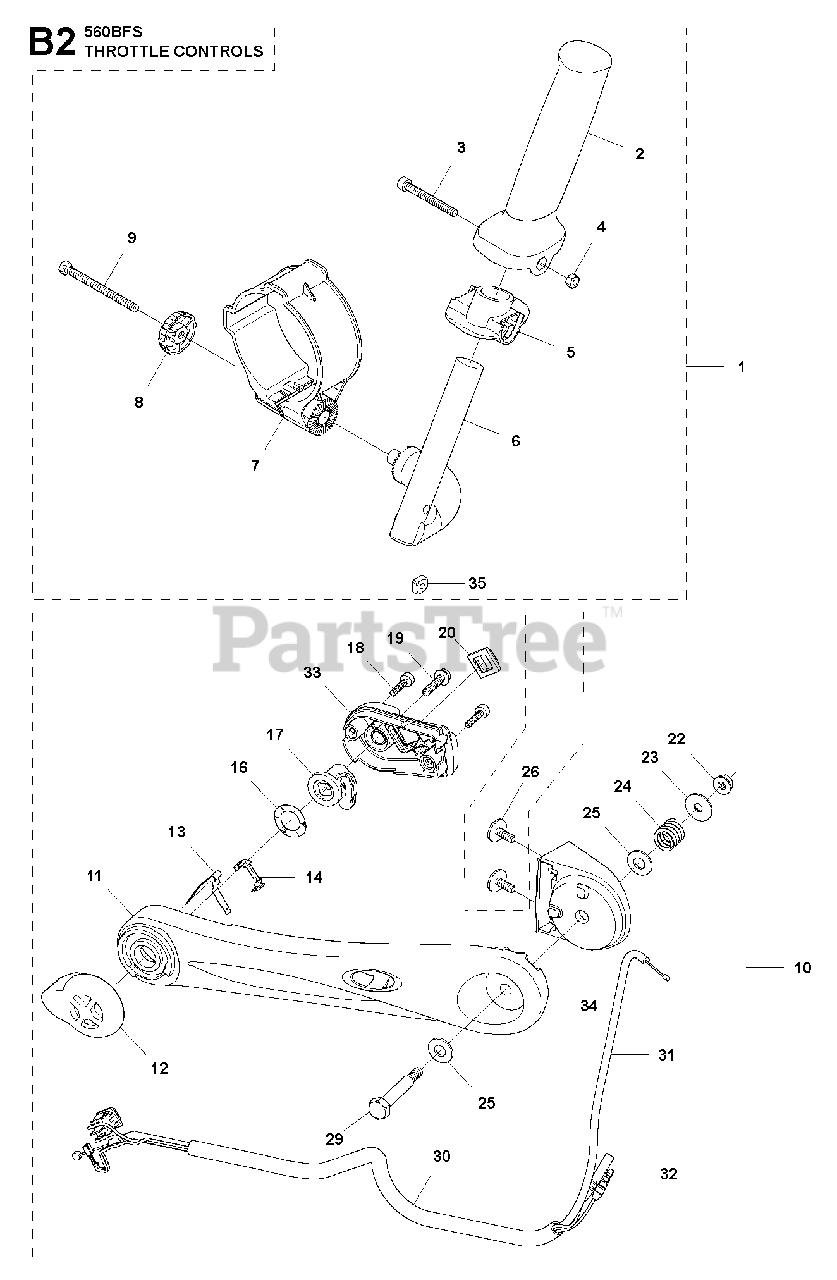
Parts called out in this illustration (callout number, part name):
2	HANDLE
3	SCREW
4	NUT
5	BRACKET
6	BRACKET
7	HANDLE HOLDER
8	KNOB
9	SCREW
11	ARM
12	LEVER,THROTTLE
13	PLATE, CONTACT
14	STOPPER
16	WASHER WAVE
17	PLATE
18	SCREW
19	BOLT
20	CAP SWITCH
22	NUT 8488646000
23	WASHER Z349525440
24	SPRING
25	WASHER
29	BOLT
30	TUBE
31	CABLE
32	SWITCH
33	COVER
34	BRACKET
35	SQUARE NUT M5
